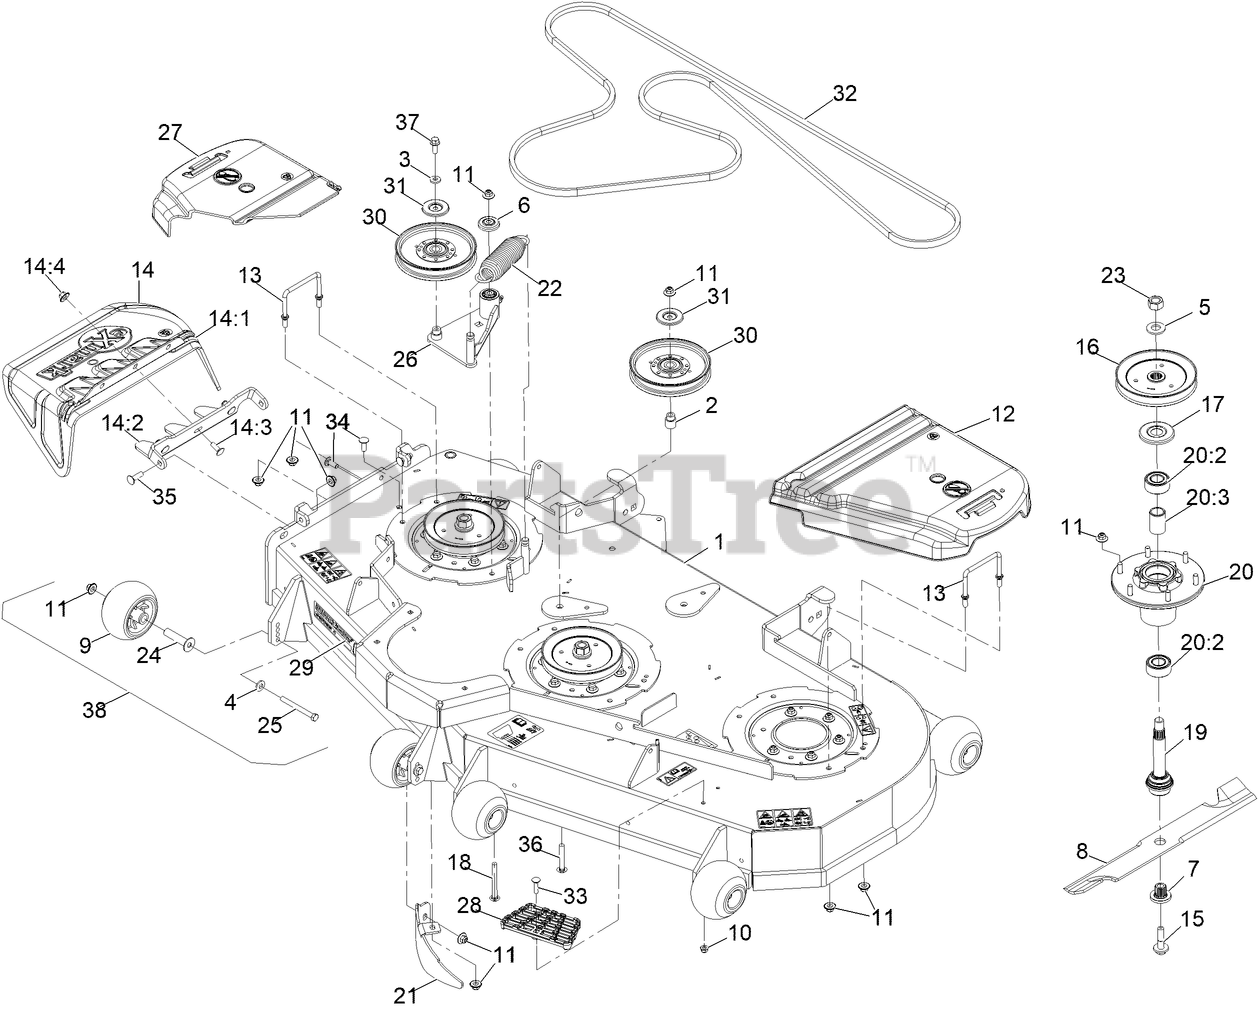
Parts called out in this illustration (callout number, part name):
1	ASM-DECK COMPLETE 603
2	BUSHING-IDLER
4	WASHER-BELLEVILLE
6	GUARD-TOP
7	BUSHING,SPLINED
8	Blade-Extreme 2, 20.50"
9	ROLLER-SCALP, ANTI
10	NUT-HF, NI
11	Nut-Nyloc 3/8-16 Flg
12	COVER-BELT, LH
13	WIREFORM-COVER
14	ASM,DISCHARGE CHUTE
14:1	CHUTE,DISCHARGE
14:2	BRACKET,DISCHARGE CHUTE
14:3	SCREW-CARR
14:4	Nut-Nyloc 3/8-16 Flg
15	SCREW,SEMS 1/2-20 X 2.19
16	SHEAVE,BLADE DRIVE 6.50
17	GUARD-BEARING, TOP
18	BOLT-SHOULDER, CARRIAGE 3/8-16 X 3 1/2
19	ASM-SPINDLE AND SEAL
20	ASM-CUTTER HSG
20:2	BEARING-3205 TRASHGUARD
20:3	SPACER-BEARING
21	DOGLEG - LZ60
22	SPRING-EXTENSION
23	NUT-HEX
24	AXLE, ROLLER
25	SCREW-HH 3/8-16 X 3 3/4 GR 8
26	IDLER ARM ASM
27	BELTSHIELD-RT, 60
28	STEP-DECK
29	DECAL, 604
30	IDLER-PULLEY
31	SHIELD-DUST
33	Bolt-Carriage 5/16-18 X 1 1/4
34	SCREW-CARR
35	Bolt-Carriage 3/8-16 X 1 1/4
36	SCREW-CARR
37	SCREW-HHF
38	KIT, ANTI-SCALP ROLLER
